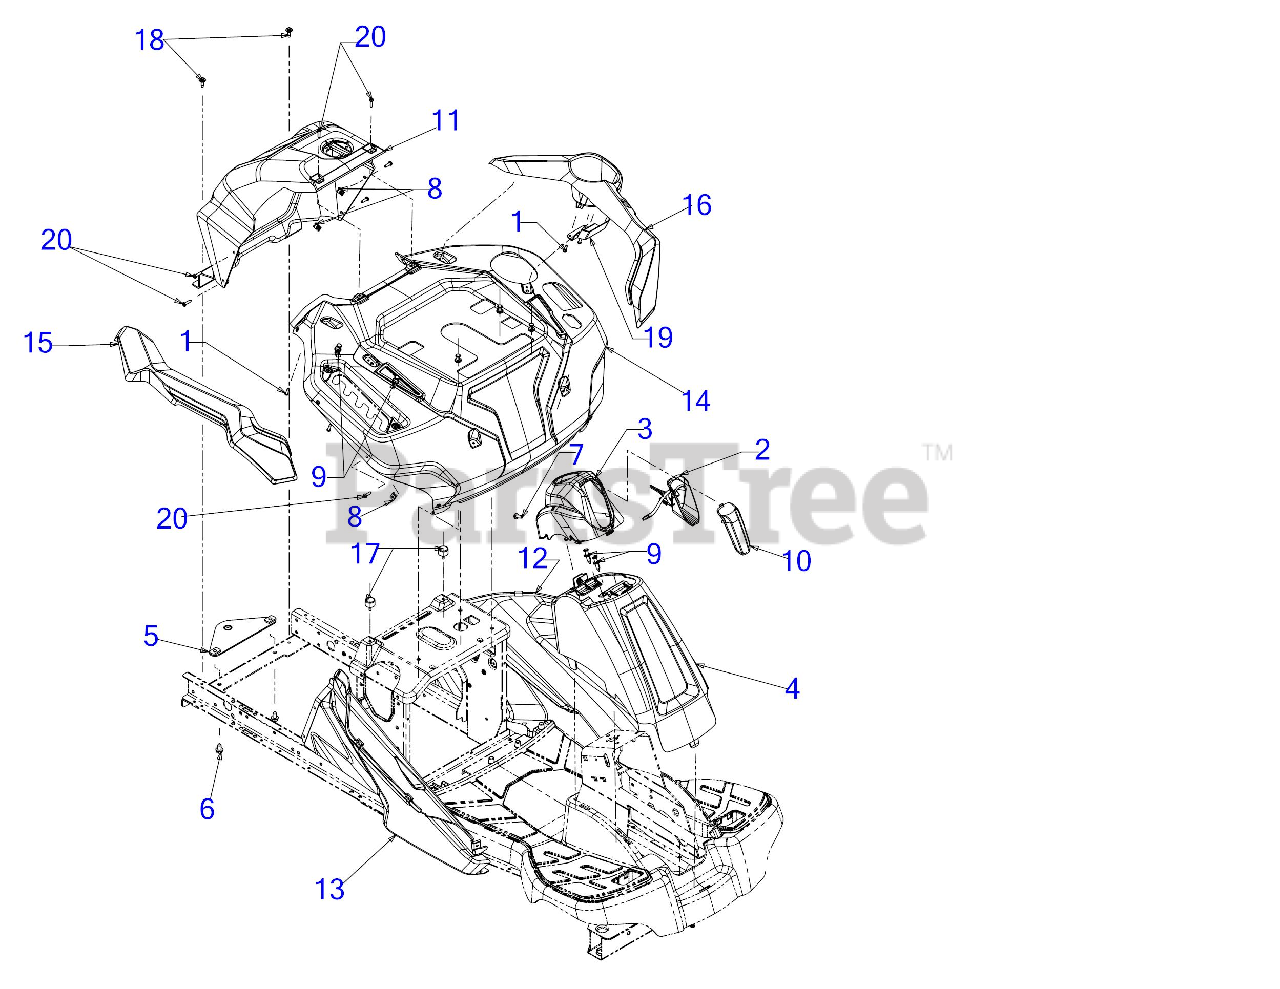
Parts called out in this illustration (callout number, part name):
1	SCREW, #8-16X.750 PH TORX COMBO
2	HEADLIGHT HARNESS ASSEMBLY
3	COLUMN CAP
4	COLUMN COVER
6	SCREW 5/16-18 x .625
7	SCREW 1/4-20X.75
9	PLASTIC RIVET
10	LED HEADLIGHT LENS
11	REAR BODY COVER
12	BODY PANEL (LH)
13	BODY PANEL (RH)
15	FENDER TRIM (RH)
16	FENDER TRIM (LH)
17	BUMPER .62 DIA x .50
18	SHOULDER SCREW M6-1 .368 X.115
20	SCREW 10-6 x .75
